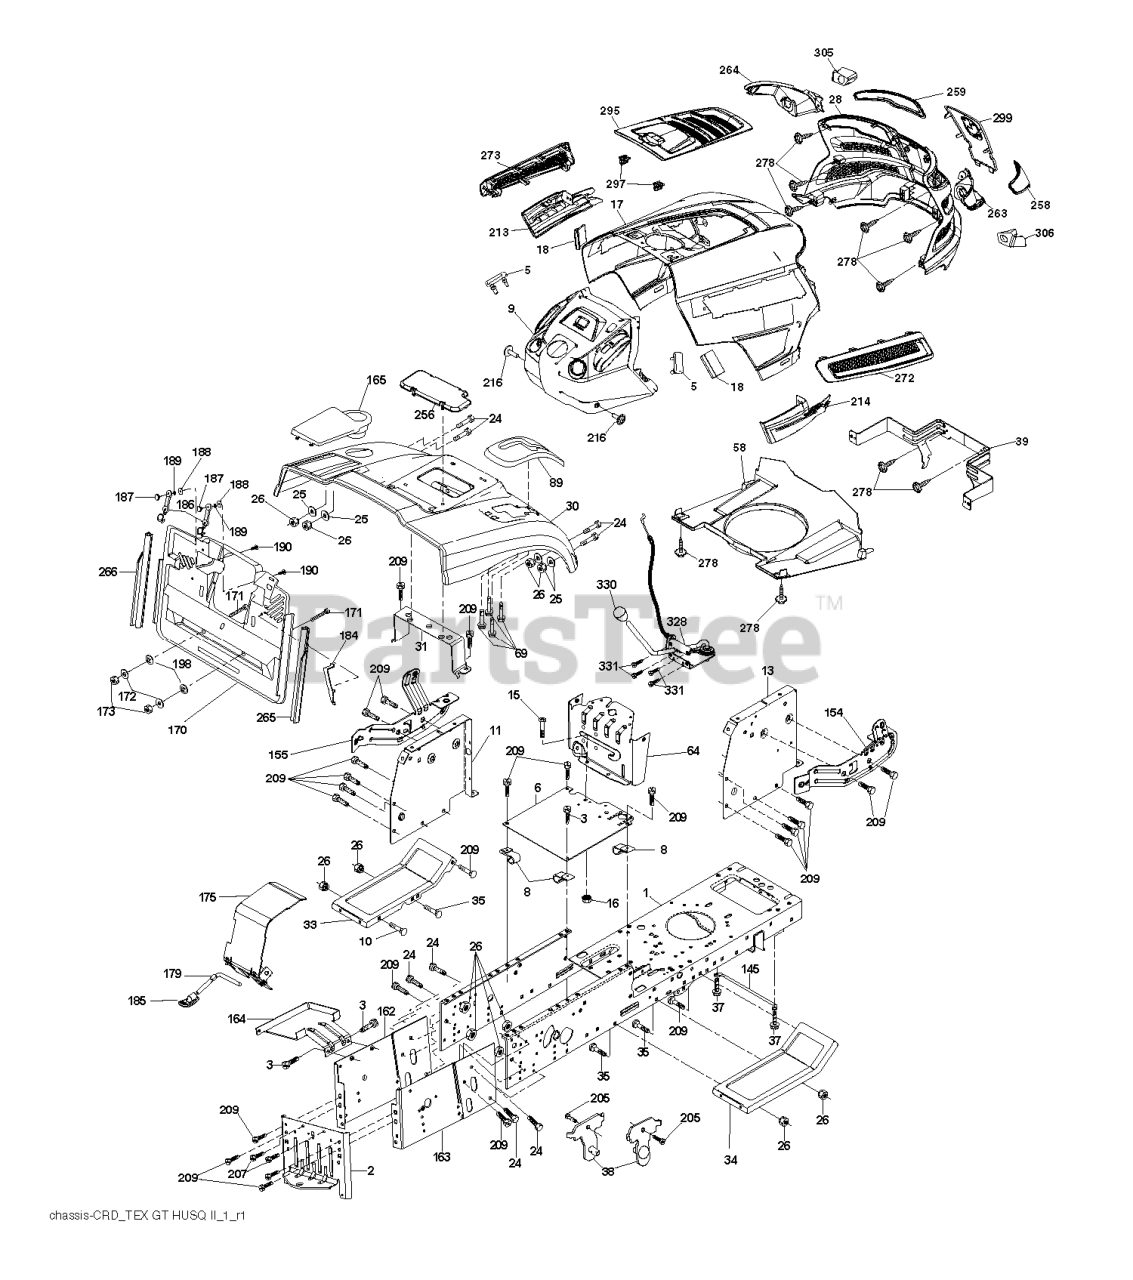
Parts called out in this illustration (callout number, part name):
2	DRAWBAR
3	SCREW 3/8-16X3/4
5	BUMPER DASH
6	PLATE
8	CLIP,INSULATOR
9	DASH.UPPR.GT2.CRD.SM.PTO.MC.HR
10	BOLT D
11	PANEL DASH LH
13	PANEL DASH RH
15	Screw, Machine, Truss Head 5/16-18 UNC x 3/4
16	NUT
17	HOOD.ASM.HUSQVARNA.GT.TEX.ORAN
18	BUMPER.HOOD.TEX.HUSQVARNA
24	BOLT
25	WASHER
26	NUT
28	GRILLE.SUBASM.GT.HUSQ.II
30	CONSOLE.CRD.AUTO.GRY
31	BRACKET SUPPORT FENDER
33	FOOTREST PNT LH
34	FOOTREST PNT RH
35	BOLT
37	Screw 5/16-18 x 1/2 Hex, Self Tapping 5/16-18 x 1/2
38	BRACKET ASM PIVOT MOWER REAR
39	BRACKET.PIVOT.HOOD.GT.HUSQ.II
58	AIR.DUCT.GTV.BLACK
69	SCREW.HI-LO.CONSOLE
89	CONSOLE.CRD.AUTO.GREY.2005
145	ROD.PIVOT.HOOD
162	BRACKET
163	BRACKET EXTEN CHASSIS RH CRD
165	COVER.BATTERY.BGGR.ELE
171	BOLT
172	WASHER
175	DOOR TRAP
179	ROD PIVOT FBI
184	BRACKET.ACTUATOR.BAGGER.SRD
186	LATCH ASSY
187	WELDNUT
189	LOCKWASHER #10
190	SCREW
205	SCREW LT
207	SCREW, 5/16-18 X 1/2
209	SCREW, 3/8-16X3/4
213	SIDE.TRIM.LH.GT.HUSQ.II.GRAY
214	SIDE.TRIM.RH.GT.HUSQ.II
216	SCREW 14-20 X 5/8
256	COVER FENDER CRD
258	LENS.HEADLIGHT.RH.GTII.2011
259	LENS.HEADLIGHT.LH.GTII.2011
263	BEZEL LIGHT.RH.GT.II.MYLAR
264	BEZEL LIGHT.LH.GT.II.MYLAR
265	SEALING
266	SEALING
272	VENT.SIDE.RH.GT.HUSQ.II.
273	VENT.SIDE.LH.GT.HUSQ.II.498
278	SCREW.#10 X 0.750.BOS
297	CLIP.RETAINER.TINNER.
299	APPLIQUE.SUBASM.GT.HUSQ.II
305	INSERT.REFLECTIVE.LH.HUSQ.GTII
306	INSERT.REFLECTIVE.RH.HUSQ.GTII
330	RP KNOB.OVAL.TAPERED.3/8-16BLK
331	SCREW.#10-24X5/8.RN.QU
